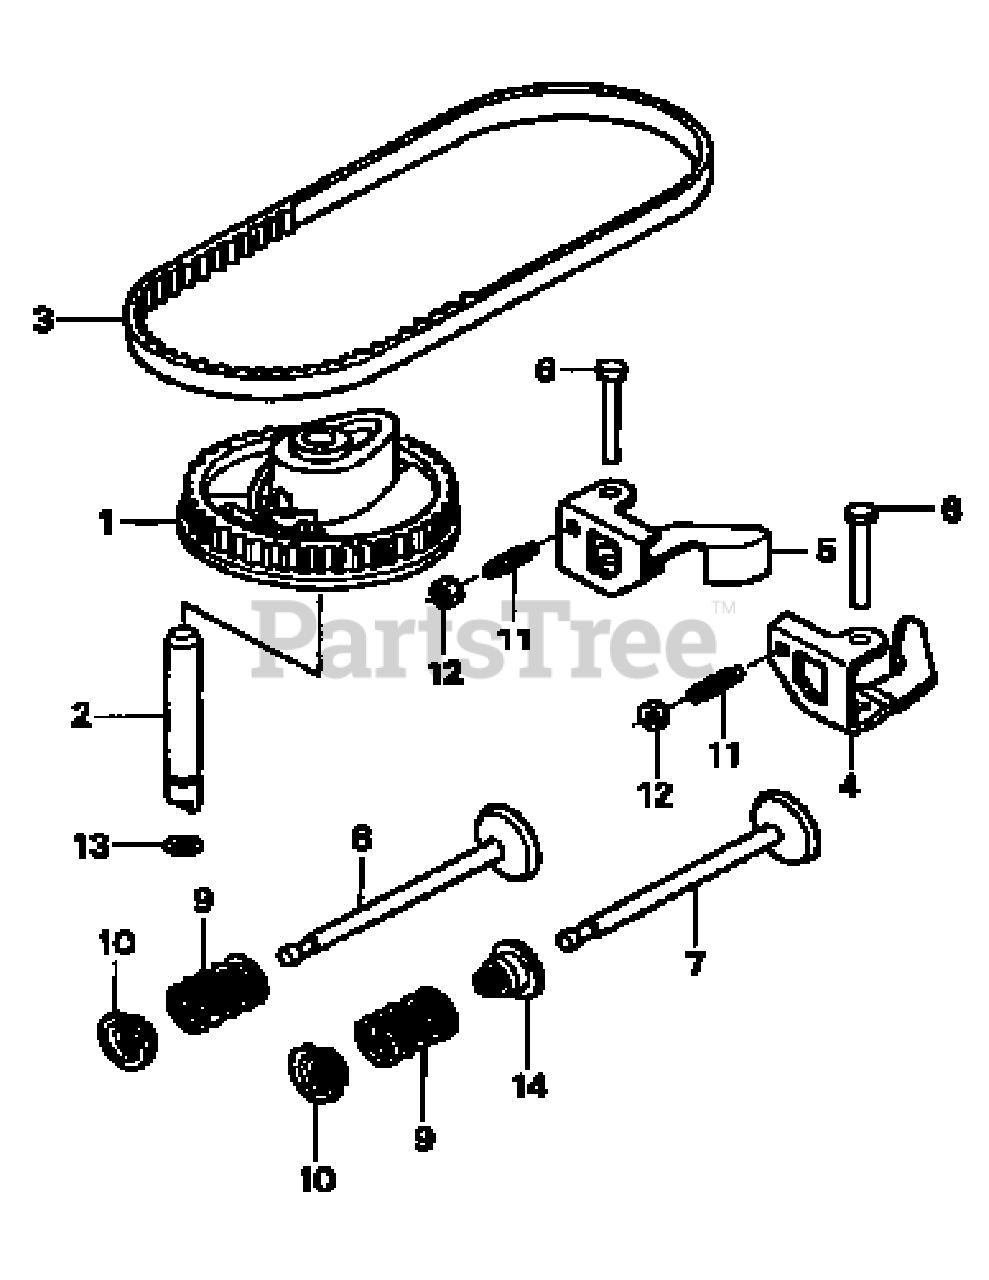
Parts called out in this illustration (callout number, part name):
1	Camshaft Pulley
2	Cam Pulley Shaft
3	Timing Belt
4	Valve Rocker Arm (Intake)
5	Valve Rocker Arm (Exhaust)
6	Rocker Arm Shaft
7	Intake Valve
8	Exhaust Valve
9	Valve Spring
10	Valve Spring Retainer
11	Tappet Adjustment Screw
12	Tappet Adjustment Nut
14	Valve Stem Seal
